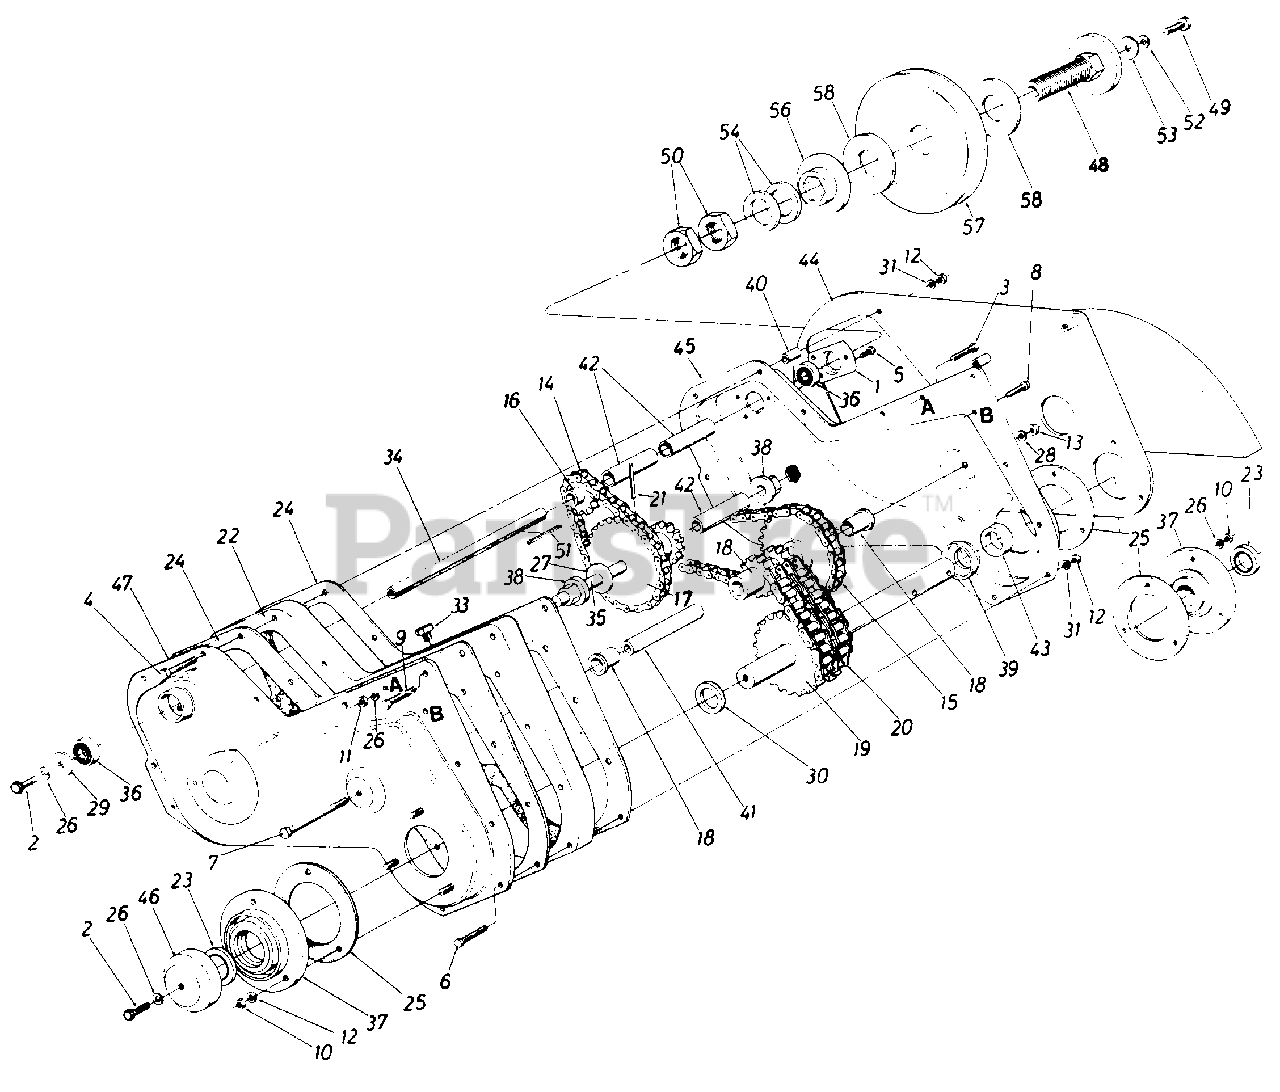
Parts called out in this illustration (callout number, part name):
1	Bearing Housing 1-3/8" Dia.
2	Hex Bolt 5/16-18 x .88" Lg. Spec.
3	Hex Bolt 5/16-18 x 1.50" Lg.
4	Hex Bolt 1/4-20 x 2.75" Lg.
5	Hex Wash. S-Tap. Scr. 1/4-20 x .50" Lg.
6	Hex B0lt 1/4-20 x 1.50" Lg.
7	Hex Bolt 3/8-16 x 4.5" Lg.
8	Hex Wash. Hd. Bolt 1/4-20 x 1.5" Lg.
9	Hex Wash. TT Tap Scr. 5/16-18 x 1.75" Lg.
10	Hex Cent. L.-Nut 5/16-18 Thd.
11	Hex Nut 5/16-18 Thd.
12	Hex Nut 1/4-20Thd.
13	Hex Nut 3/8-16 Thd.
14	#41 Chain 1/2" Pitch x 34 Links-Endless
15	#42 Chain 1/2" Pitch x 48 Links-Endless
16	Sprocket 10 Tooth .500" Pitch
17	10 & 28 Teeth Sprocket Ass'y.
18	8-2 & 28 Sprocket Sleeve Ass'y
19	18-2 Sprocket Shaft Ass'y.
20	#50-2 Chain 5/8" Pitch x 28 Links-Endless
21	Spring Pin Spir. 1/4" Dia. x 1.50" Lg.
22	Spacer Block-Tiller Housing
23	Oil Seal Double Lip-1-1/4" Dia.
24	Gasket for Tiller Housing
25	Gasket for Brg.-Housing
26	L.-Wash. 5/16" I.D.
27	Fl.-Wash. .640" I.D. x 1.24" O.D.
28	L.-Wash. 3/8" I.D. Heavy Duty
29	Fl.-Wash. .344" I.D. x.1.125"
30	Special Washer
31	L.-Wash. 1/4" I.D.
33	Vent Plug
34	Jack Shaft .525" I.D. x 7.78"Lg.
35	Sprocket Shaft .63" Dia. x 5.0"Lg.
36	Ball Brg. .62" I.D. x 1.38" O.D.
37	Bearing Housing-1-1/4"
38	Hex Flange Brg.
39	Spacer 1.25" I.D. x 2.0" O.D.
40	Spacer.28" I.D. x .62" O.D. x .90" Lg.
41	Spacer.38" I.D. x .62" O.D. x 3.44" Lg.
42	Spacer.62" I.D. x.88" O.D. x 1.56" Lg.
43	Spacer 1.25" I.D. x 1.62" O.D. x . 50" Lg.
46	Dust Cap .320" Dia. Hole
49	Hex Bolt 5/16-18 x 1.25" Lg. Grade 5
50	Hex Jam Nut 1.0-14 x 28 Thd.
51	Sq. Key 3/16 x 1.50" Lg.
52	L.-\l\/ash. 5/16" I.D.
53	Fl.-Wash. .344" I.D. x 1.125" 0. D.
54	Spring Bell Wash. 1.0" I.D. x 2.0" O.D.
56	Floating Disc 3-1/4" O.D. x 1.0" 1. D.
57	5/8 V-Pulley 1.50" I.D. x 6.50"
58	F riction Pad 3-1/4" O. D . x 1-3/8" I.D.
